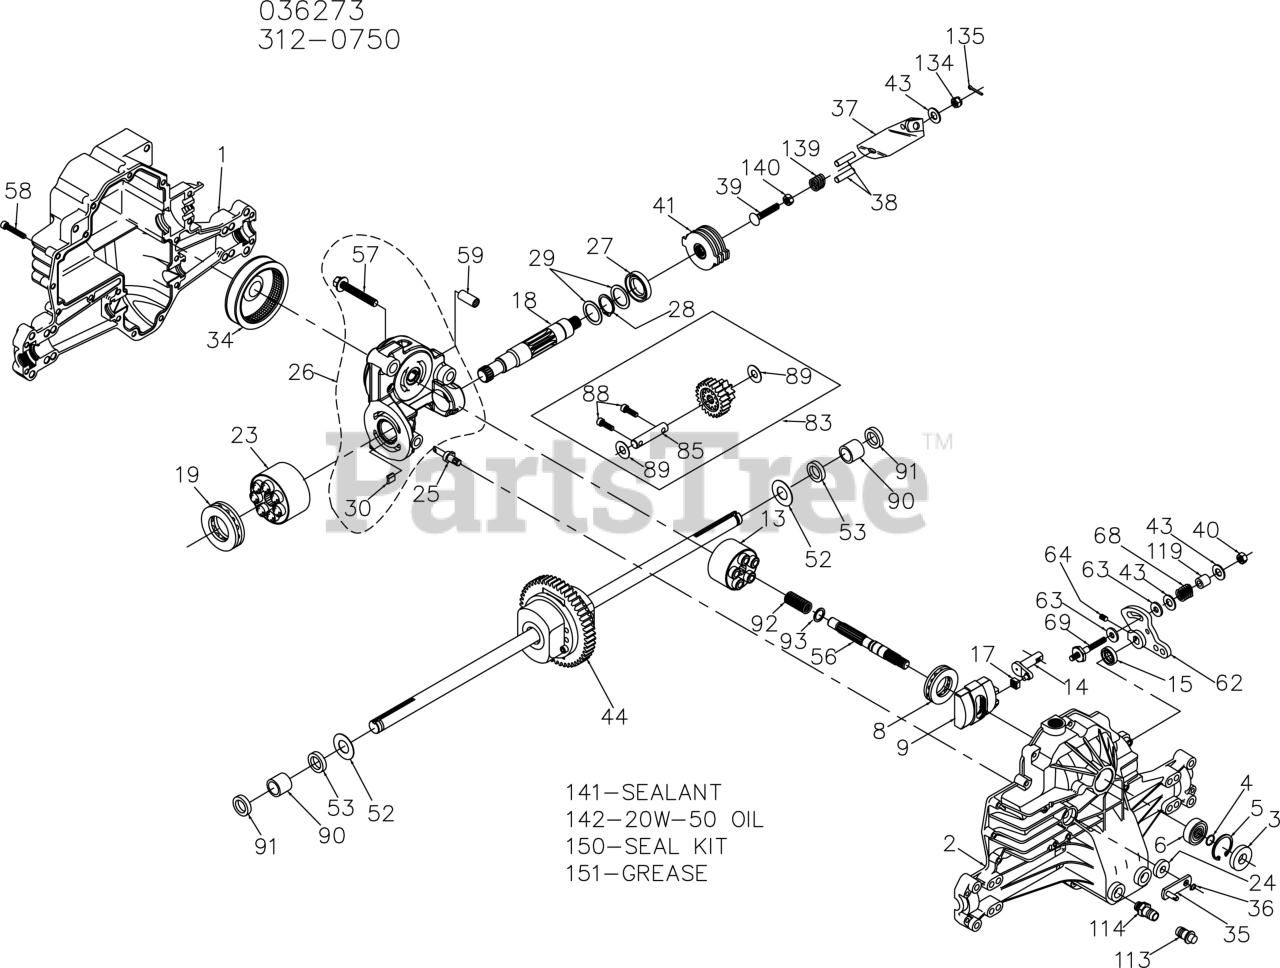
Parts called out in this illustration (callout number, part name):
1	HSG, 0650 LOWER
2	KIT, HSG UPPER
3	SEAL, LIP 15X35X7
4	RING, WIRE RETAINING
5	RING. RETAINING
6	BEARING, SHAFT BALL
8	BEARING. THRUST 30 X 52 X 13
9	SWASHPLATE. VARIABLE
13	KIT, 10 CC BLOCK
14	ARM, TRUNNION 10 CC
15	SEAL, LIP 12X25X7
17	GUIDE. SLOT
18	SHAFT, MOTOR 1O T
19	BRG, THRUST BALL 42X68X16
23	ASSEMBLY BLOCK
24	SEAL, LIP
25	ACTUATOR, BYPASS
26	KIT, C-SECTION
27	SEAL, LIP 26X42X8
28	RETAINING RING
29	WASHER 1.0X1.37X.04
30	KIT, BYPASS PLATE
35	ARM. BYPASS
36	RING, RETAINING
37	ARM, BRAKE
38	PIN, BRK .3X1.25 PLATED
39	RHCS 5/16-24X2 SQ NECK PT
40	NUT, HEX 5/16-24 NYLON
41	KIT, SRVC BRAKE ROTOR/STA
43	WASHER
44	KIT, SRVC DIFF
52	WASHER .75X1.5X.03
53	SEAL, LIP .75X1.25X.25
56	SHAFT, INPUT
57	HFHCS 3/8-24X2.5 (PATCH)
58	THCS-STAP 1/4-20X1.4
59	PIN-HOLLOW .39X.5X1.
62	ARM, CNTRL PM
63	PACK, FRICTION
64	SCREW, SET 5/16-24 60
68	SPRING, HELICAL COMP
69	STUD, DB END 5/16-24X2.5
83	KIT, SRVC JACK SHAFT/PINN
85	SHAFT, JACK
88	SHCS M6X20 (PATCH)
89	WASHER .5X1.0X.032
90	BUSHING .75X1.0X.84
91	SEAL, LIP .75X1X.158
92	SPRING. BLOCK
93	WASHER. THRUST .59 X .79 X .04
113	CAP-VENT .50
114	FTG-STR .50 O-RING
119	SPACER .32X.59X.50
140	NUT, HEX 5/16-24
141	SEALANT TUBE 10.1OZ.
142	FLUID, HYDRO 20W50 QT
142	FLUID, HYDRO 15W50 QT
150	KIT, SEAL
151	GREASE TUBE
